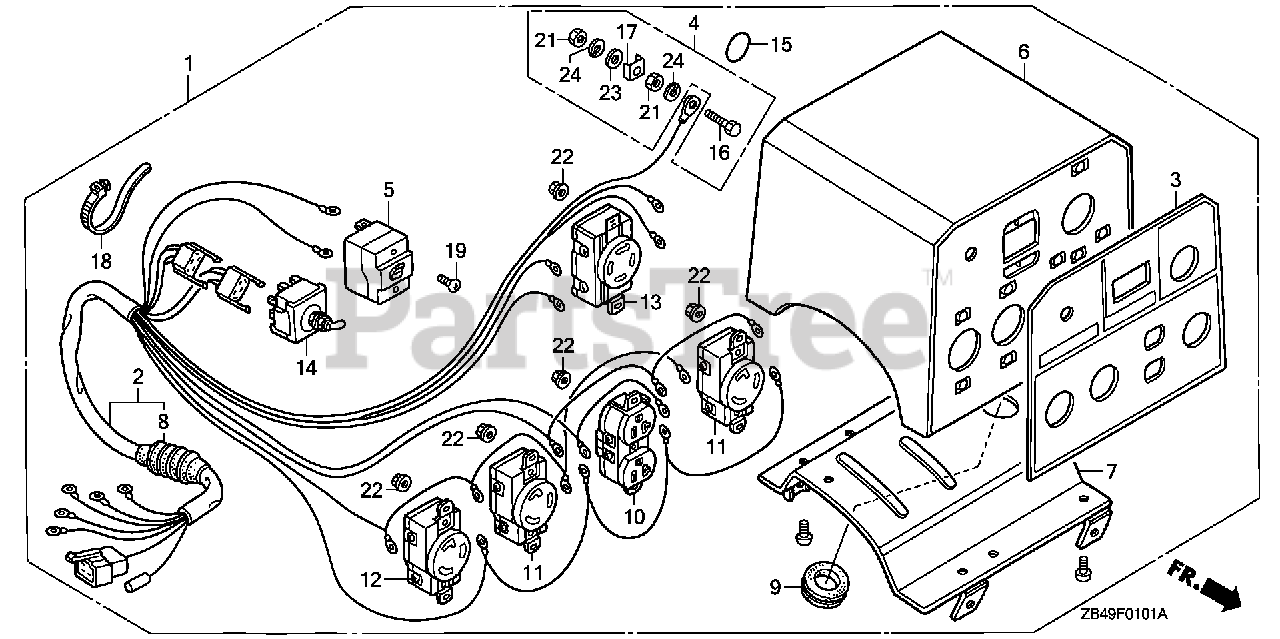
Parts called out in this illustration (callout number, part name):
1	BOX ASSY., CONTROL *R8* (BRIGHT RED)
2	WIRE HARNESS ASSY.
3	MARK, SWITCH PANEL
4	TERMINAL SET, GROUND
5	BREAKER, CIRCUIT (14A)
6	BOX, CONTROL *R280* (POWER RED)
7	PLATE (LOWER) *NH105* (MAT BLACK)
8	GROMMET, A.C. WIRE
9	GROMMET, MAIN WIRE
10	RECEPTACLE (20A/125V) (MATSUSHITA)
11	RECEPTACLE (20A/125V) (NOT AVAILABLE)
12	RECEPTACLE (30A/125V)
13	RECEPTACLE (20A-125/250V) (MATSUSHITA) (NOT AVAILABLE)
14	SWITCH ASSY., VOLT CHANGE
15	MARK, GROUND
16	BOLT, HEX. (6X28)
17	RETAINER (6MM)
18	TIE, CABLE (NATURAL 225X5.0)
19	SCREW, PAN (4X6)
21	NUT, HEX. (6MM)
22	NUT, FLANGE (4MM)
23	WASHER, PLAIN (6MM)
24	WASHER, SPRING (6MM)
